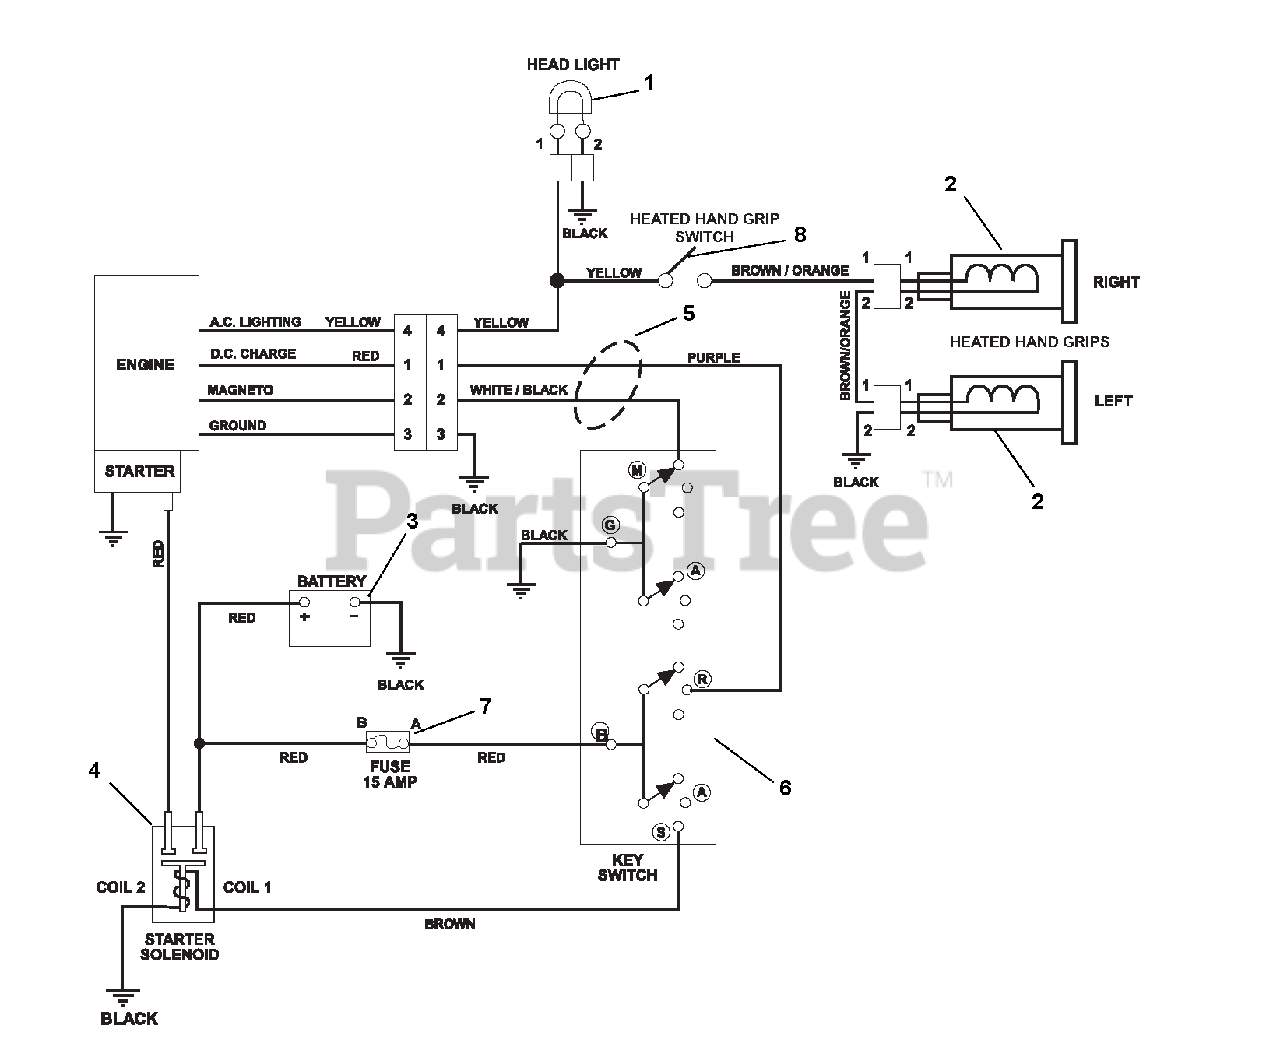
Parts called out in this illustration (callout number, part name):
1	HEADLIGHT ASSY, HALOGEN 20W
2	HEATED GRIP, MAGURA
4	SOLENOID
5	HARNESS, 12V
6	SWITCH ASSEMBLY
7	FUSE, 15 AMP.
8	SWITCH, ON/OFF
